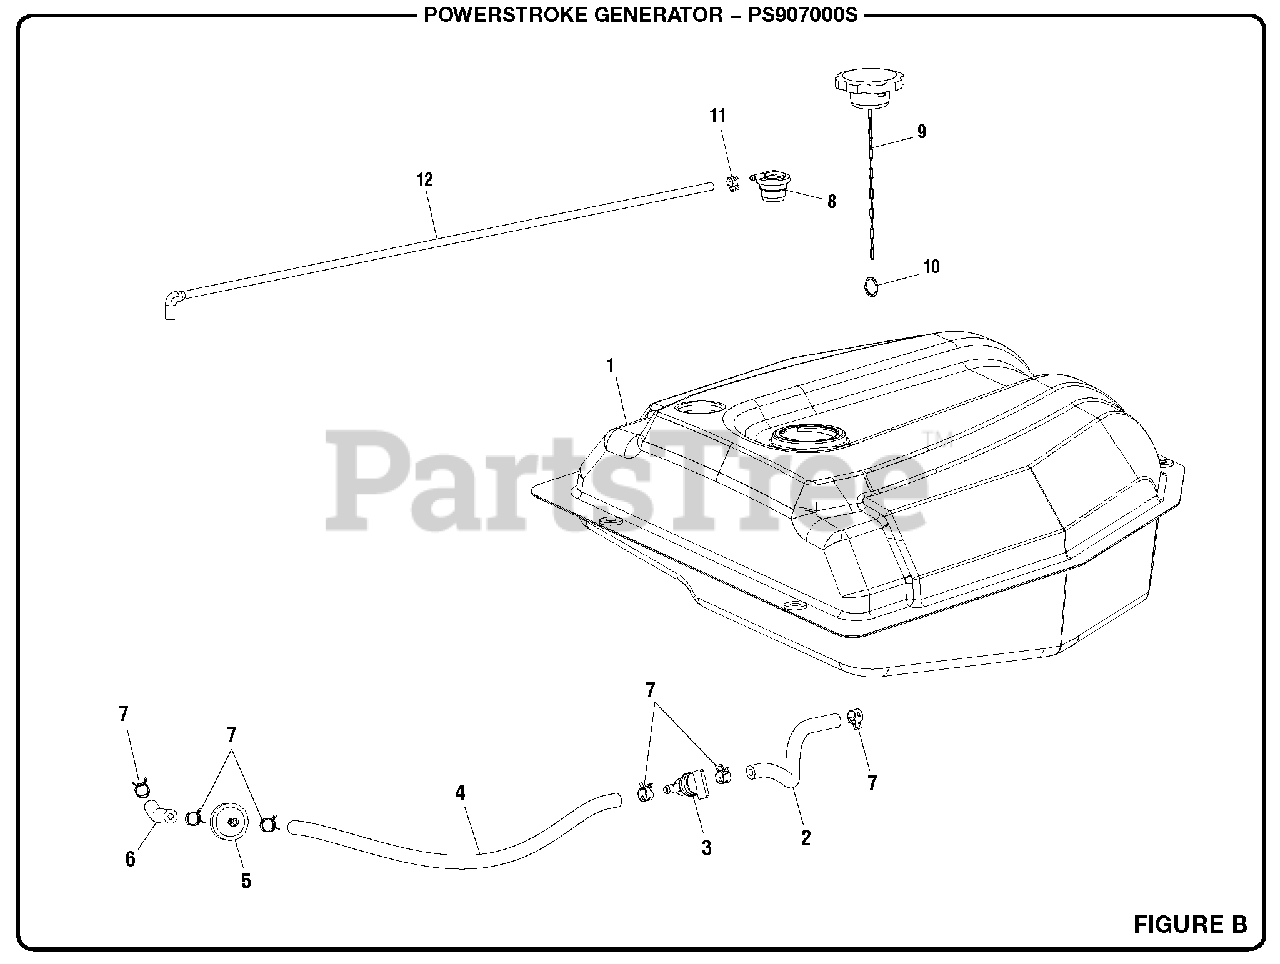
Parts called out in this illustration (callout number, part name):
1	Fuel Tank
2	Fuel Hose (55 mm)
3	Fuel Shut Off Valve
4	Fuel Hose (175 mm)
5	Fuel Filter
6	Fuel Hose (185 mm)
7	Hose Clamp (1/2 in.)
8	Vapor Vent
10	Ring Clip
11	Hose Clamp (10.3 mm)
12	Vapor Hose (590 mm)
